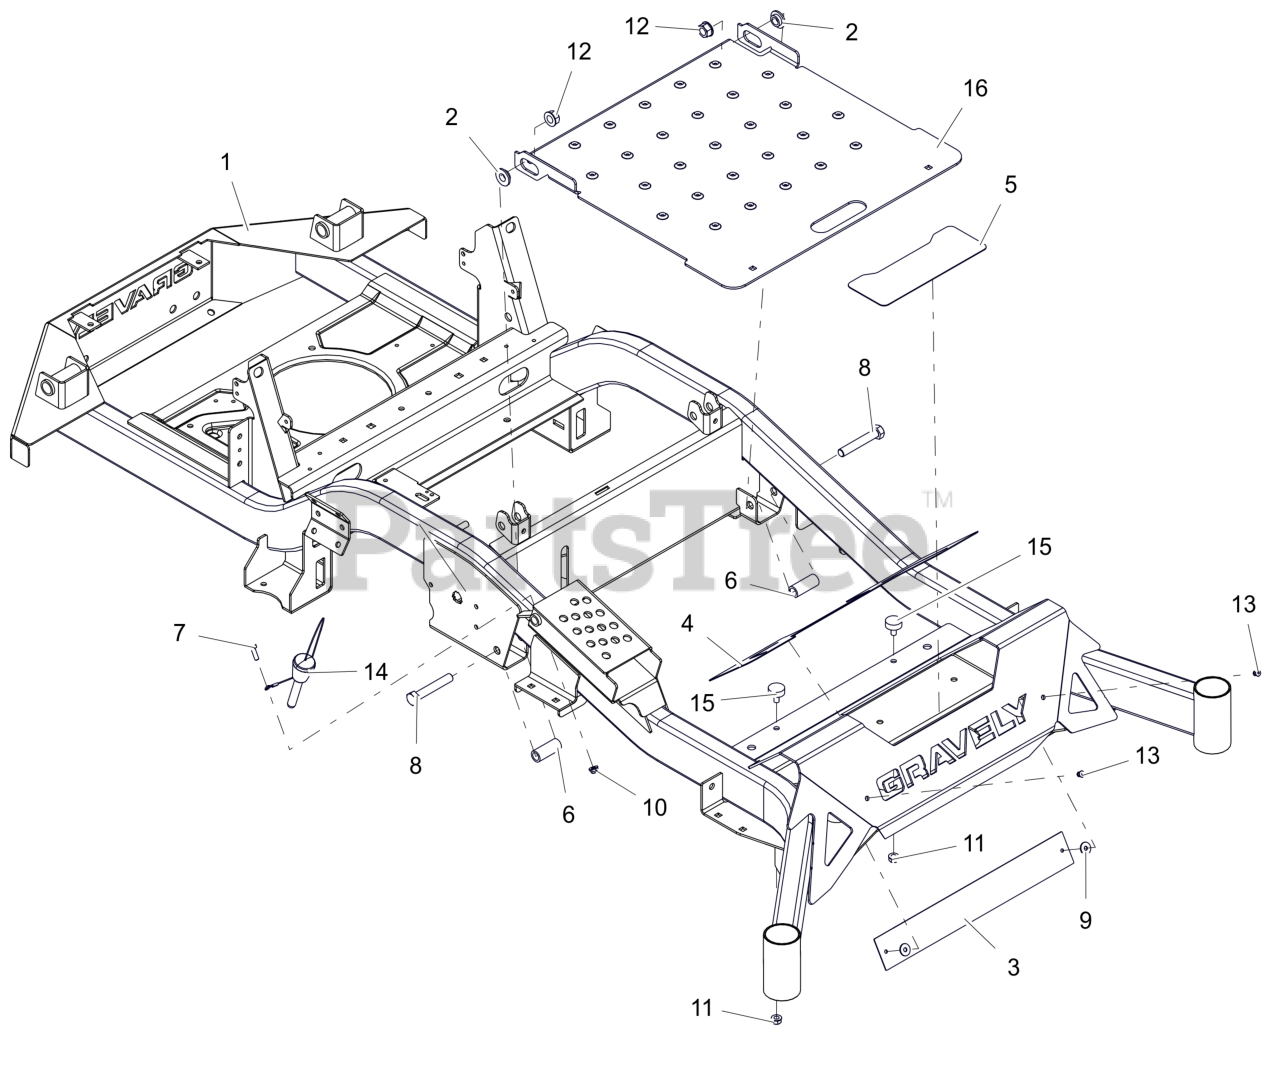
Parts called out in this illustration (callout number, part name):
1	WLDMT, MAIN FRAME -HD 60 (RED)
2	BSHG-FLG .515X.750X.310X1.120
3	PLATE, BACK FOOT-REST XL
4	GRIP, FRONT
5	GRIP, STEP
6	SPACER, .515X.75X1.83
7	BLT, HEX .25-20X.75 G5 ZCC
8	BLT, HEX .50-13X3.00 G5 ZCC
9	WSHR, RBR W/ADHESIVE .25X.75X.06
10	NUT,NYL-FLG .25-20 GF ZCC
11	NUT,SPNLK-FLG .31-18 G5 ZCC
12	NUT-LK-TOP-FLG .500-13 GF ZCC
13	RIVET, .1875 AL/AL .126-.250
14	PIN, MAGNETIC .50X2.50
15	BUMPER, RUBBER
16	KIT,ACCESS PANEL W/DECALS-RED
